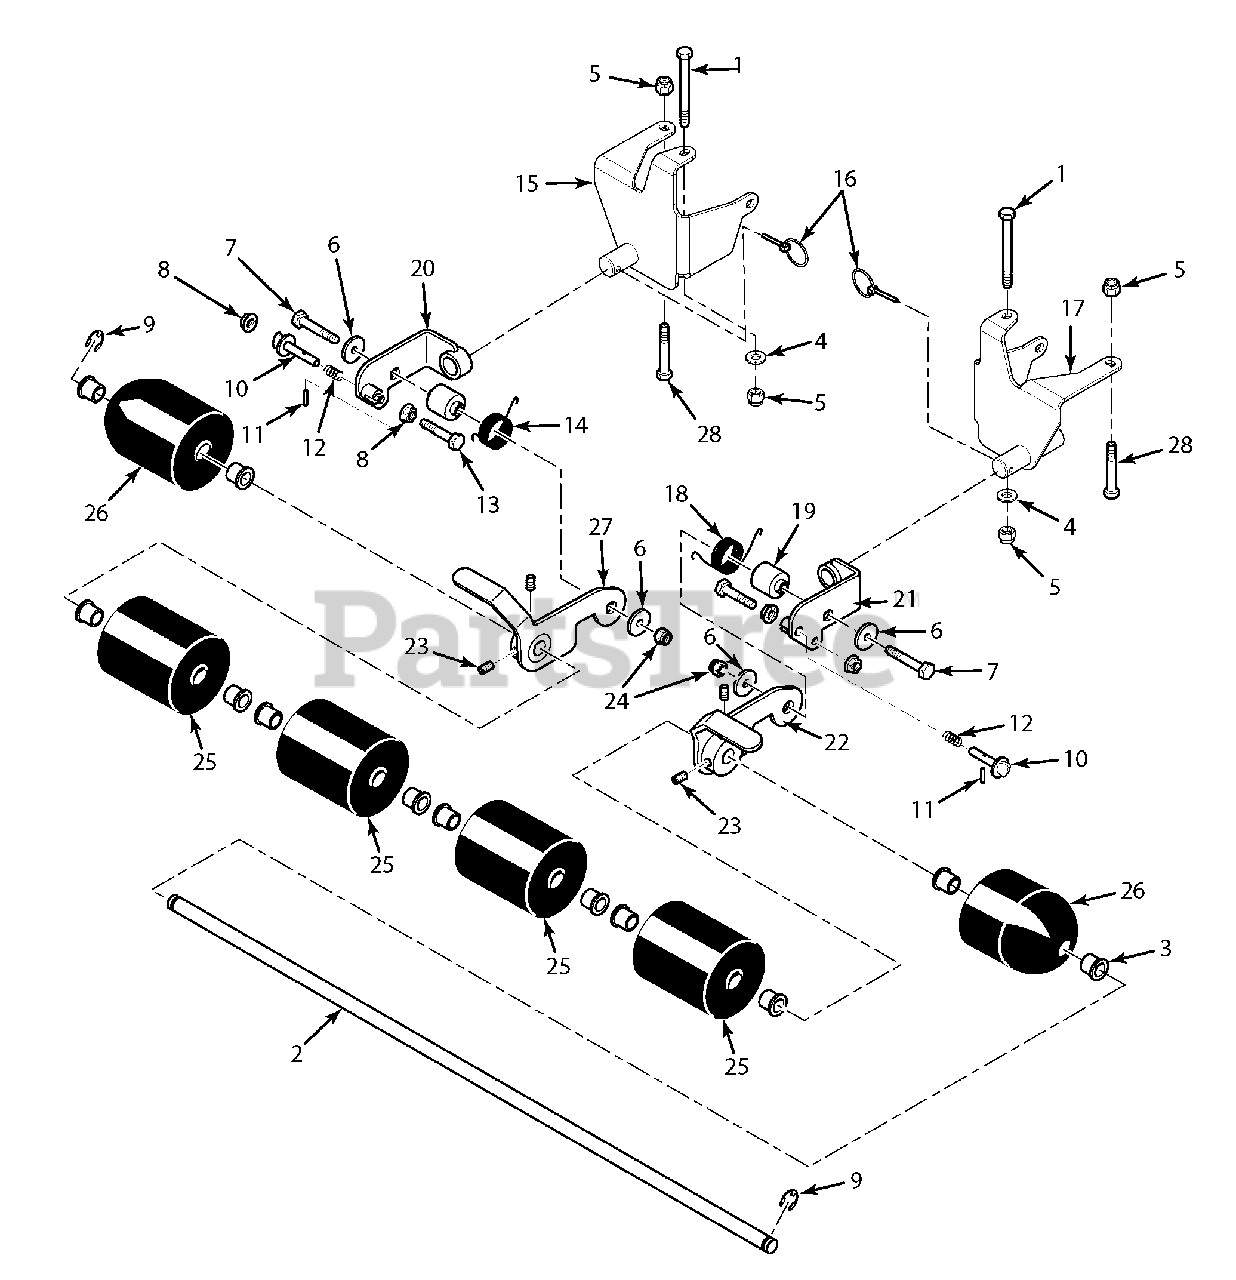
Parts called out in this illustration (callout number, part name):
1	Bolt, Hex Head 5/16-18 x 5-1/2"
2	Roller Shaft
3	Bushing, .752 Oilite
4	Flatwasher, 5/16-.378 x .875 x .083
5	Nut, Elastic Stop 5/16-18
6	Flatwasher, 3/8-.406 x 1-1/2" 7 Gauge
7	Bolt, Hex Head 3/8-16 x 2-3/4"
8	Nut, Serrated Flange 3/8-16
9	Retaining Ring, .750 External "E"
10	Pin, Lift Latch
11	Pin, Slotted Spring 5/32" x 7/8"
12	Spring, Lock Pin
13	Bolt, Hex Head 3/8-16 x 2-1/2"
14	Spring, Torsion LH
15	Mounting Bracket Weldment, LH - SCZ-48/52
16	Quick Pin, .188 Dia.
17	Mounting Bracket Weldment, RH - SCZ-48/52
18	Spring, Torsion RH
19	Hub, Striper
20	Pivot Weldment, LH
21	Pivot Weldment, RH
22	Hinge Weldment, RH
23	Set Screw, 3/8-16 x 1/2"
24	Nut, Elastic Stop 3/8-16
25	Roller Assembly
26	Roller Assembly, Striper End
27	Hinge Weldment, LH
28	Bolt, Hex Head 5/16-18 x 3-1/4"
